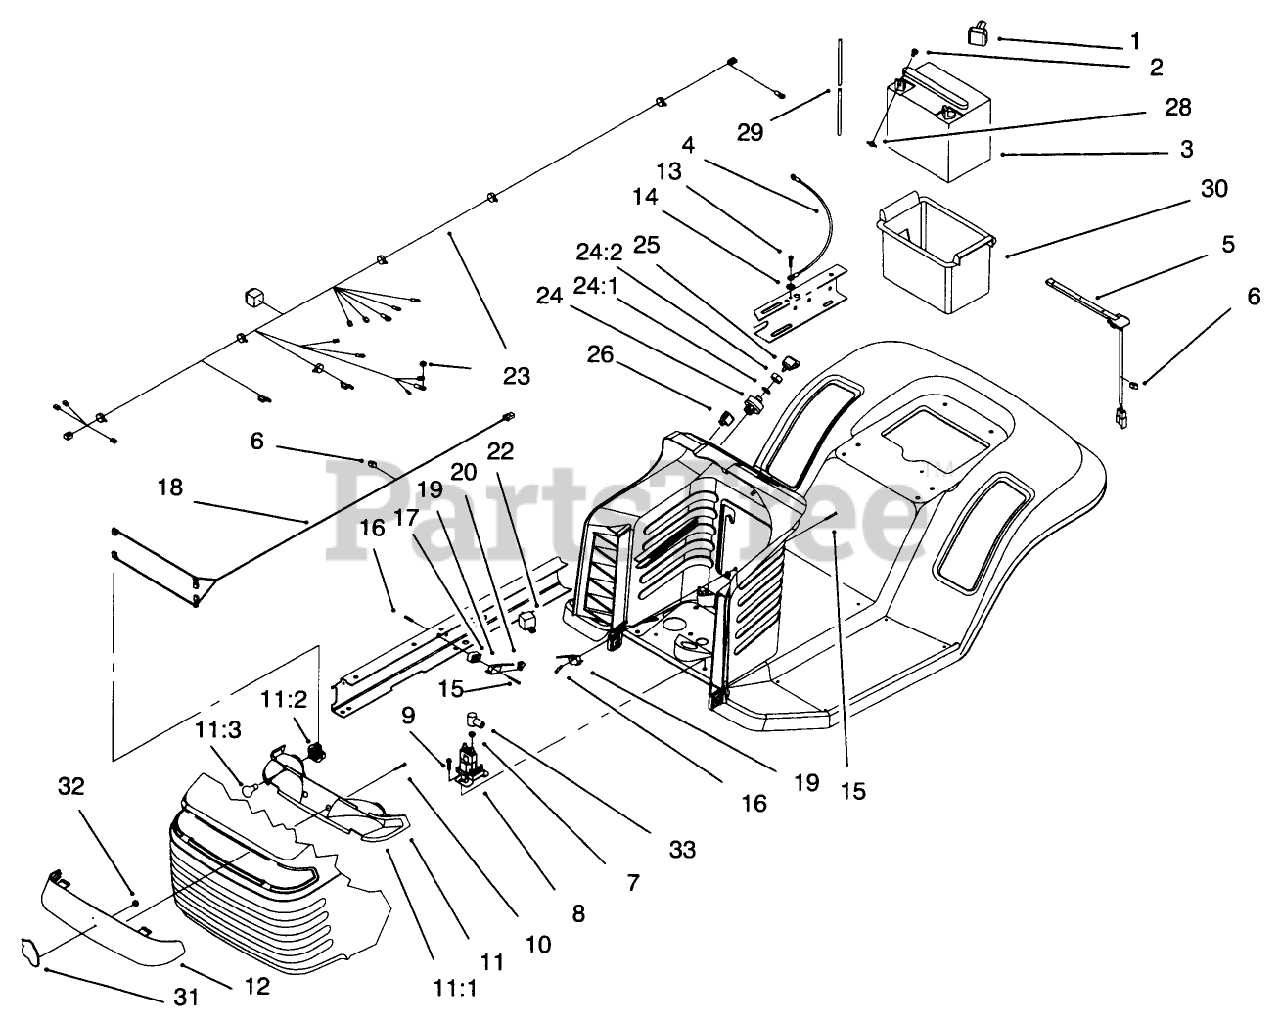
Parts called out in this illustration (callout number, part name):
1	BOOT-TERMINAL
2	SCREW-HH
4	WIRE ASM
5	SWITCH-SEAT
6	CLIP-RETAINER, WIRE
7	NUT-KEPS
9	SCREW-HWH
11	HEADLIGHT REFLECTOR ASM
11:3	BULB
12	LENS-HEADLIGHT
13	SCREW-HWH
14	WASHER-LOCK/EXT
15	SCREW-HH
16	NUT-SPEED
17	SPACER
18	HARNESS-WIRE, LIGHTS
19	SWITCH-MICRO
20	PLUNGER-SEAL
22	RELAY
23	WIRE HARNESS
24:1	WASHER-LOCK/INT
24:2	NUT-HH
25	KEY-IGNITION
26	SWITCH-ROCKER
28	NUT-WING
29	TUBE-BATT DRAIN/80-2600
30	BOX-BATTERY
33	BOOT-TERMINAL INSULATOR
